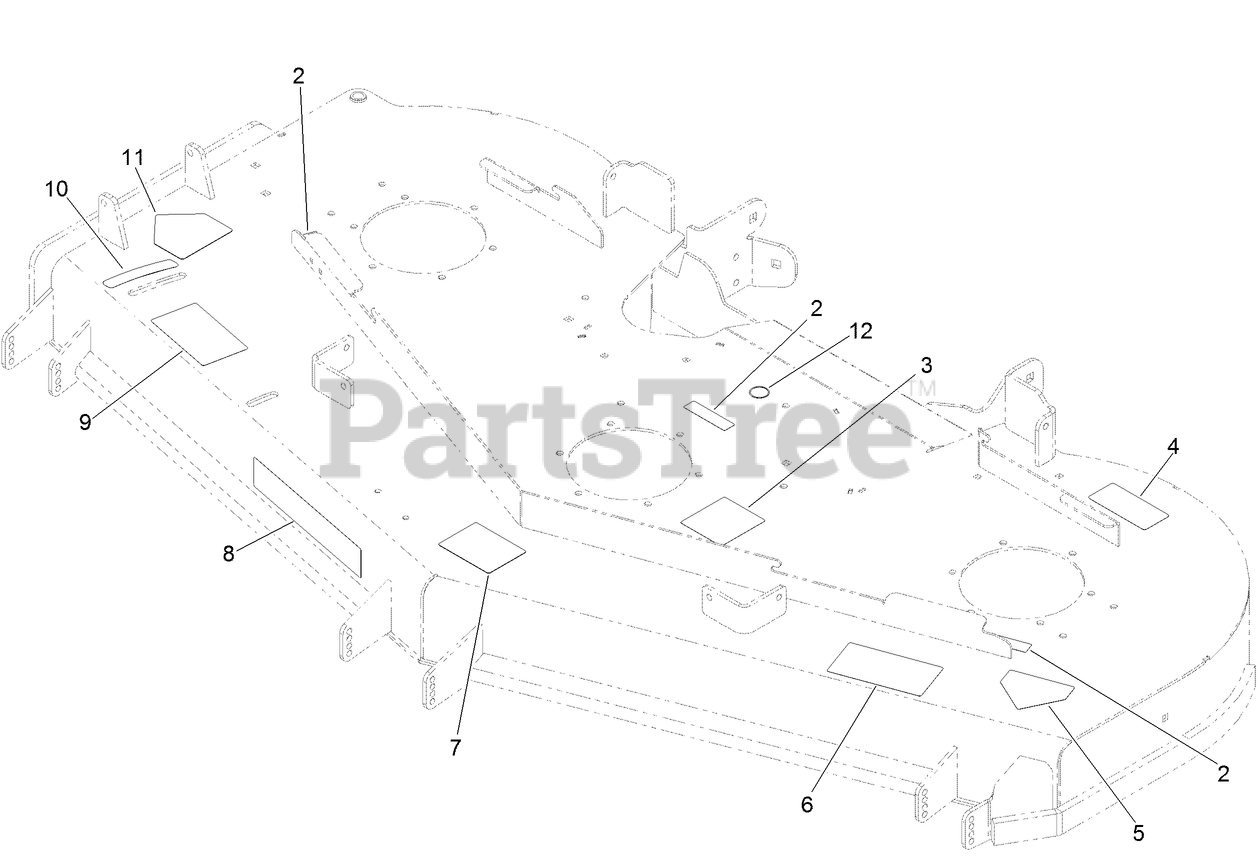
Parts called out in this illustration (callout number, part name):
2	DECAL-COVER, MISSING
3	DECAL-ROUTING, DECK BELT
4	DECAL-TORQUE
5	DECAL-DANGER
6	DECAL-DANGER, THROWN OBJECT
7	DECAL-SCALP, ANTI
9	DECAL-ADJUSTMENT, BAFFLE
10	DECAL-SETTING, BAFFLE
11	DECAL-DANGER
12	DECAL-GREASE
